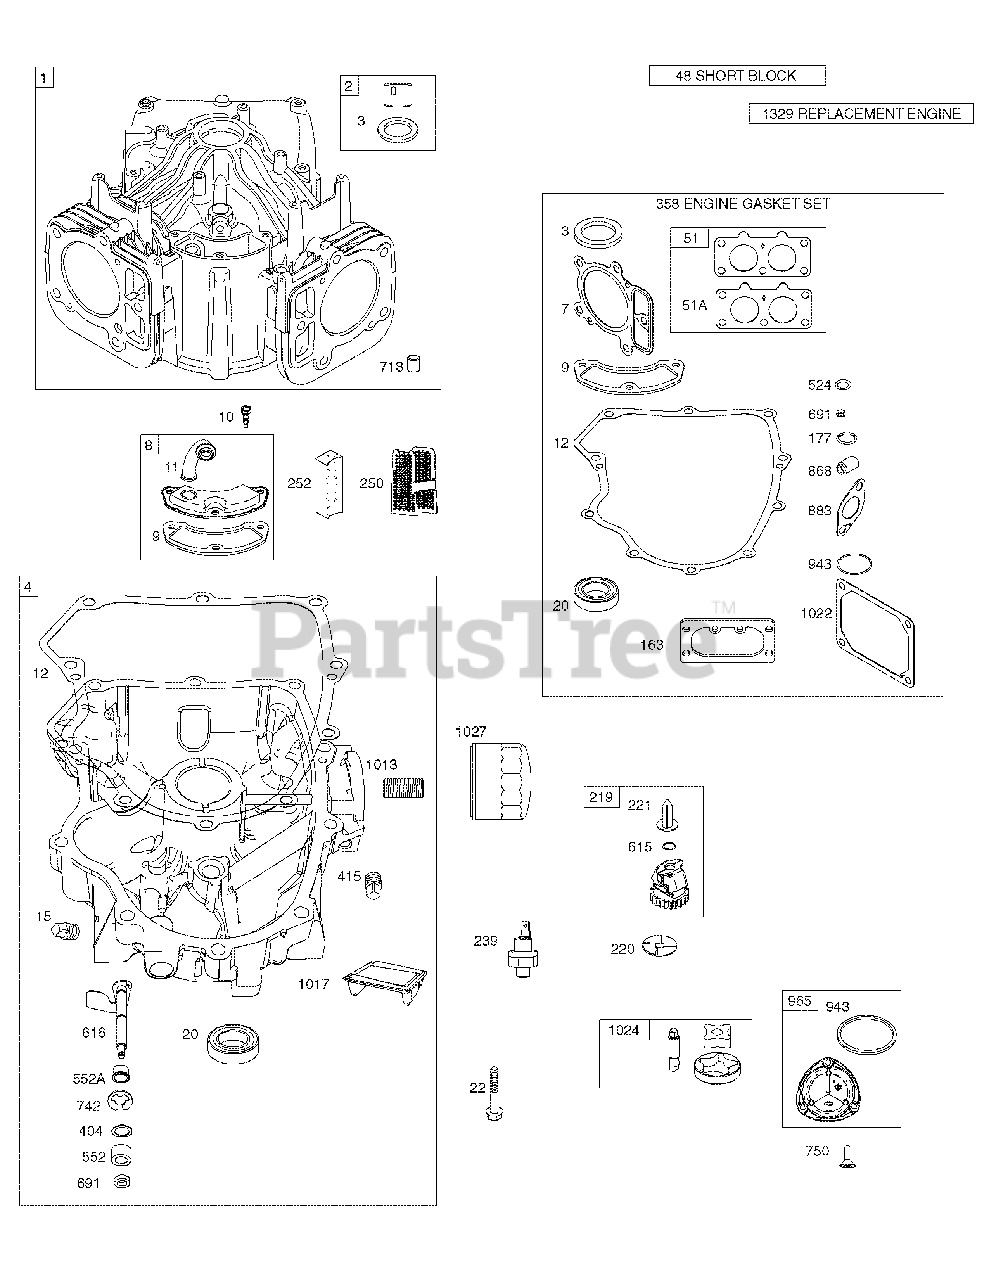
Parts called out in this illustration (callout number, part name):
1	Cylinder Assembly
2	Kit-Bushing/Seal (Magneto Side)
3	Oil Seal (Magneto Side)
4	EngineSump
5	Cylinder Head (Cylinder #1)
5A	Cylinder Head (Cylinder #2)
7	Cylinder Head Gasket
8	Breather Assembly
9	Breather Gasket
10	Screw (Breather Assembly)
11	Breather Tube
12	Crankcase Gasket
13	Screw (Cylinder Head)
15	Oil Drain Plug
16	Crankshaft
20	Oil Seal (PTO Side)
22	Screw (Crankcase Cover/Sump)
23	Flywheel
24	Flywheel Key
25	Piston Assembly (Standard)
25	Piston Assembly (.020" Oversize)
26	Ring Set (Standard)
26	Ring Set (.020" Oversize)
27	Piston Pin Lock
28	Piston Pin
29	Connecting Rod
32	Screw (Connecting Rod)
33	Exhaust Valve
34	Intake Valve
35	Valve Spring (Intake)
36	Valve Spring (Exhaust)
40	Valve Retainer
42	Valve Keeper
45	Valve Tappet
48	Short Block
50	Intake Manifold
51	Intake Gasket
51A	Intake Gasket
53	Stud (Carburetor)
54	Screw (Intake Manifold)
73	Rotating Screen
74	Screw (Rotating Screen)
75	Washer (Flywheel)
95	Screw (Throttle Valve)
98	Idle Speed Kit
104	Float Hinge Pin
105	Float Needle Valve
108	Choke Valve
117	Main Jet (Standard) (Left Jet)
117A	Main Jet (Standard) (Right Jet)
118	Main Jet (High Altitude) (Left Jet)
118A	Main Jet (High Altitude) (Right Jet)
121	Carburetor Overhaul Kit
125	Carburetor
130	Throttle Valve
131	Throttle Shaft Kit
133	Carburetor Float
135	Fuel Transfer Tube
137	Float Bowl Gasket
141	Choke Shaft Kit
142	Carburetor Nozzle
146	Timing Key
150	Nozzle Gasket
163	Air Cleaner Gasket
165	Nut (Ring Gear)
177	O-Ring Seal (Dipstick)
187	Fuel Line (Cut to Required Length)
188	Screw (Control Bracket)
192	Rocker Arm Adjuster
197	Screw (Back Plate)
209	Governor Spring (Yellow/Black)
211	Governed Idle Spring (Orange)
212	Throttle Link
216	Choke Link
217	Choke Return Spring
219	Governor Gear
220	Washer (Governor Gear)
221	Governor Cup
222	Control Bracket
227	Governor Control Lever
231	Screw (Choke Valve)
239	Oil Pressure Switch
240	Fuel Filter
250	Breather Retainer
252	Oil Collector
265	Casing Clamp
267	Screw (Casing Clamp)
276	Sealing Washer (Fuel Solenoid)
278	Washer (Governor Control Lever)
287	Screw (Dipstick Tube)
304	Blower Housing
305	Screw (Blower Housing)
305A	Screw (Blower Housing to Intake Elbow)
306	Cylinder Shield (Cylinder #2)
307	Screw (Cylinder Shield) (1.4-20 x 2.3)
309	Starter Motor
310	Screw (Starter Motor)
332	Nut (Flywheel)
333	Magneto Armature
334	Screw (Magneto Armature)
337	Spark Plug
358	Engine Gasket Set
385	Screw (Fuel Pump)
387	Fuel Pump
404	Washer (Governor Crank)
415	Plug (Oil Pressure Switch)
418	Carburetor Plate
431	Intake Elbow
445	Air Cleaner Cartridge Filter
447	Screw (Air Guide Cover) 10-24 x 7.16)
447A	Screw (Air Guide Cover)
467	Air Cleaner Knob
474	Alternator
501	Regulator
503	Starter Strap
505	Nut (Governor Control Lever)
510	Starter Drive
513	Drive Clutch
523	Dipstick
524	Dipstick Tube Seal
525	Dipstick Tube
526	Screw (Regulator)
544	Starter Armature
552	Governor Crank Bushing
552A	Governor Crank Bushing
562	Screw (Governor Control Lever)
573	Back Plate
579	Nut (Starter Cable)
601	Hose Clamp (Black)
601A	Hose Clamp (Green)
615	Governor Shaft Retainer
616	Governor Crank
617	O-Ring Seal (Intake Manifold) (Red)
628	Screw (Fuel Pump Bracket)
633	Choke Seal/Throttle Shaft
635	Spark Plug Boot
654	Nut (Carburetor)
668	Spacer (Rotating Screen)
668A	Spacer (Rotating Screen)
672	Carburetor Plate Gasket
691	Governor Shaft Seal
695	Screw (Ring Gear)
697	Screw (Drive Cap)
718	Locating Pin
741	Timing Gear
742	E-Ring Retainer (Governor Crank)
750	Screw (Oil Pump Cover)
783	Pinion Gear
788	Fuel Pump Bracket
789	Wiring Harness
798	Screw (Rocker Arm)
803	Starter Housing
847	Dipstick/Tube Assembly
851	Spark Plug Terminal
865	Air Guide Cover (Cylinder #1)
865A	Air Guide Cover (Valley)
868	Valve Seat
877	Alternator Wire/Connector
877A	Alternator Wire/Connector
883	Exhaust Gasket
914	Screw (Rocker Cover)
918	Vacuum Hose
943	O-Ring Seal (Oil Pump Cover)
947	Fuel Solenoid
965	Oil Pump Cover
967	Pre-Cleaner Filter
968	Air Cleaner Cover
975	Float Bowl
987	Throttle Shaft Seal
1005	Flywheel Fan
1013	Oil Filter Nipple
1017	Oil Pump Screen
1022	Rocker Cover Gasket
1023	Rocker Cover (Cylinder #1)
1023A	Rocker Cover (Cylinder #2)
1026	Push Rod (Exhaust)
1026A	Push Rod (Intake)
1027	Oil Filter
1029	Rocker Arm
1036	Emissions Label
1040	Trim Plate
1051	Retaining Ring (Starter Drive)
1059	Screw/Washer Kit (Alternator)
1070	Screw (Flywheel Fan)
1090	Brush Retainer
1095	Valve Gasket Set
1100	Rocker Arm Pivot
1119	Screw (Alternator)
1124	O-Ring Seal (Fuel Transfer Tube)
1124A	O-Ring Seal (Fuel Transfer Tube)
1126	Screw (Fuel Transfer Tube)
1127	Screw (Fuel Bowl)
1128	Screw (Carburetor Nozzle)
1169	Screw (Carburetor Plate)
1329	Replacement Engine
